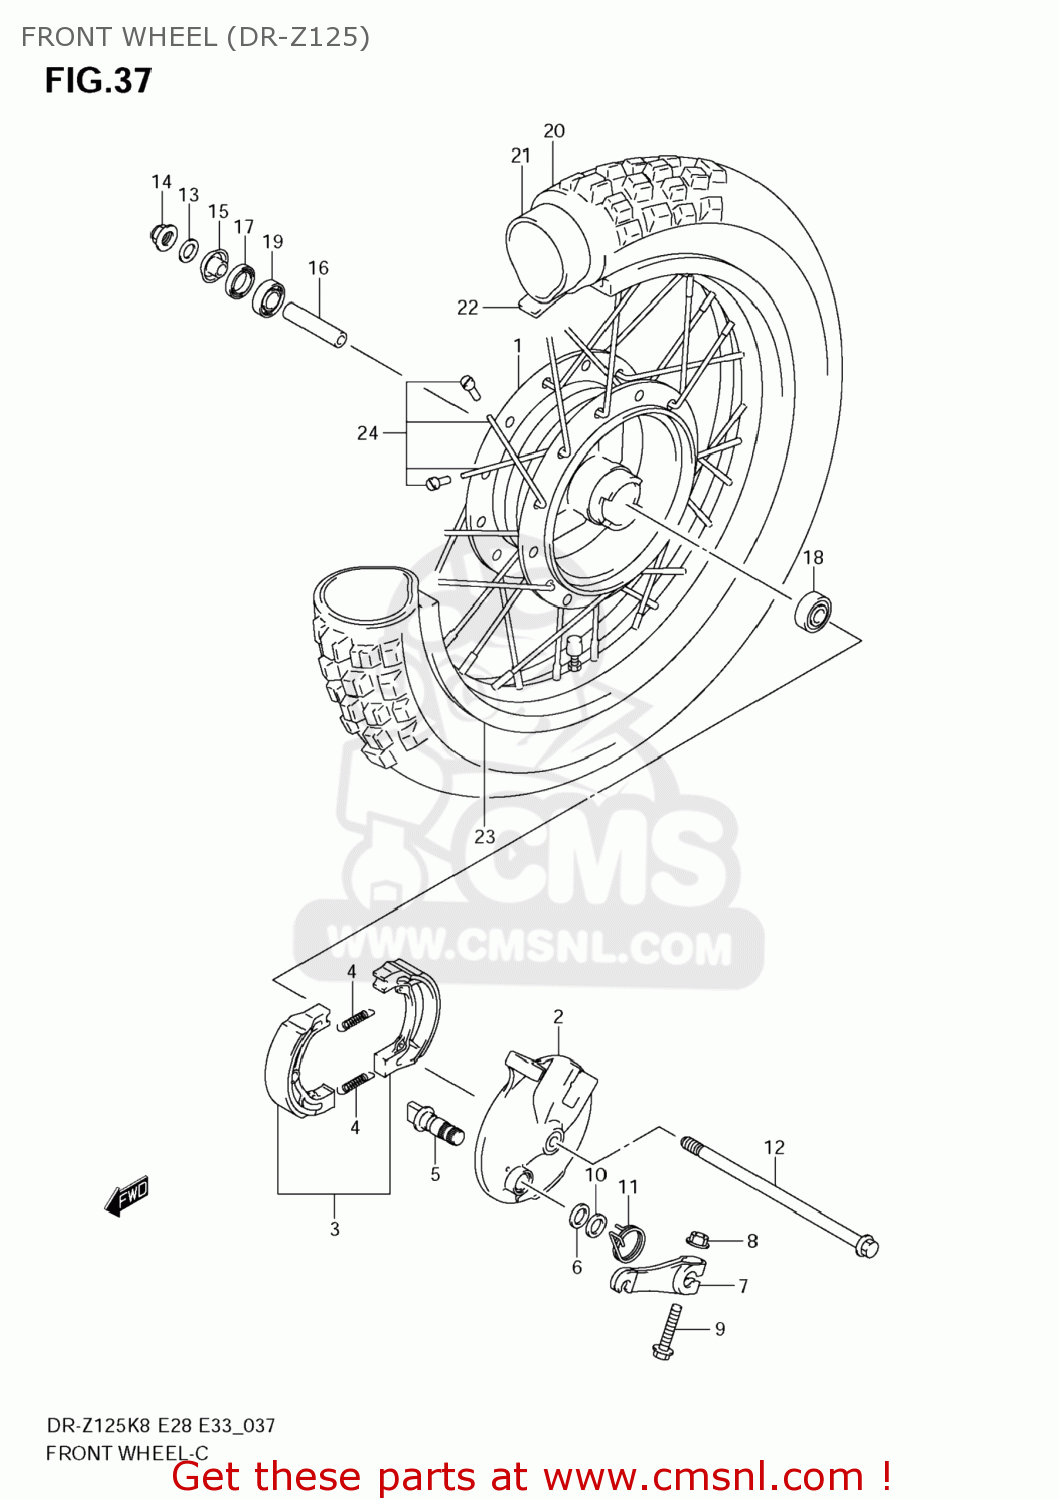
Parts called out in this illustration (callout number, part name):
1	HUB,FR WHEEL
2	PANEL,FR BRAKE ANCHOR
3	SHOE & SPRING SET,BRAKE (NAS)
4	SPRING
5	CAM,FR BRAKE
6	O RING(D:2.5,ID:13.8)
7	LEVER,FR BRAKE CAM
8	NUT
9	BOLT
10	WASHER(14.5X22X1.6)
11	SPRING,FR BK CAM LEVER RETURN
12	AXLE,FR
13	WASHER(10.5X20X3.2)
14	NUT
15	SPACER,FR AXLE,R
16	SPACER(10.1X16X51)
17	SEAL,OIL(15X31X5)
18	BEARING
19	BEARING
20	TIRE,FR
21	TUBE ASSY,WHEEL INNER
22	PROTECTOR,WHL INR TUBE
23	RIM,FR WHEEL(17X1.40)
24	SPOKE SET,FR WHEEL
